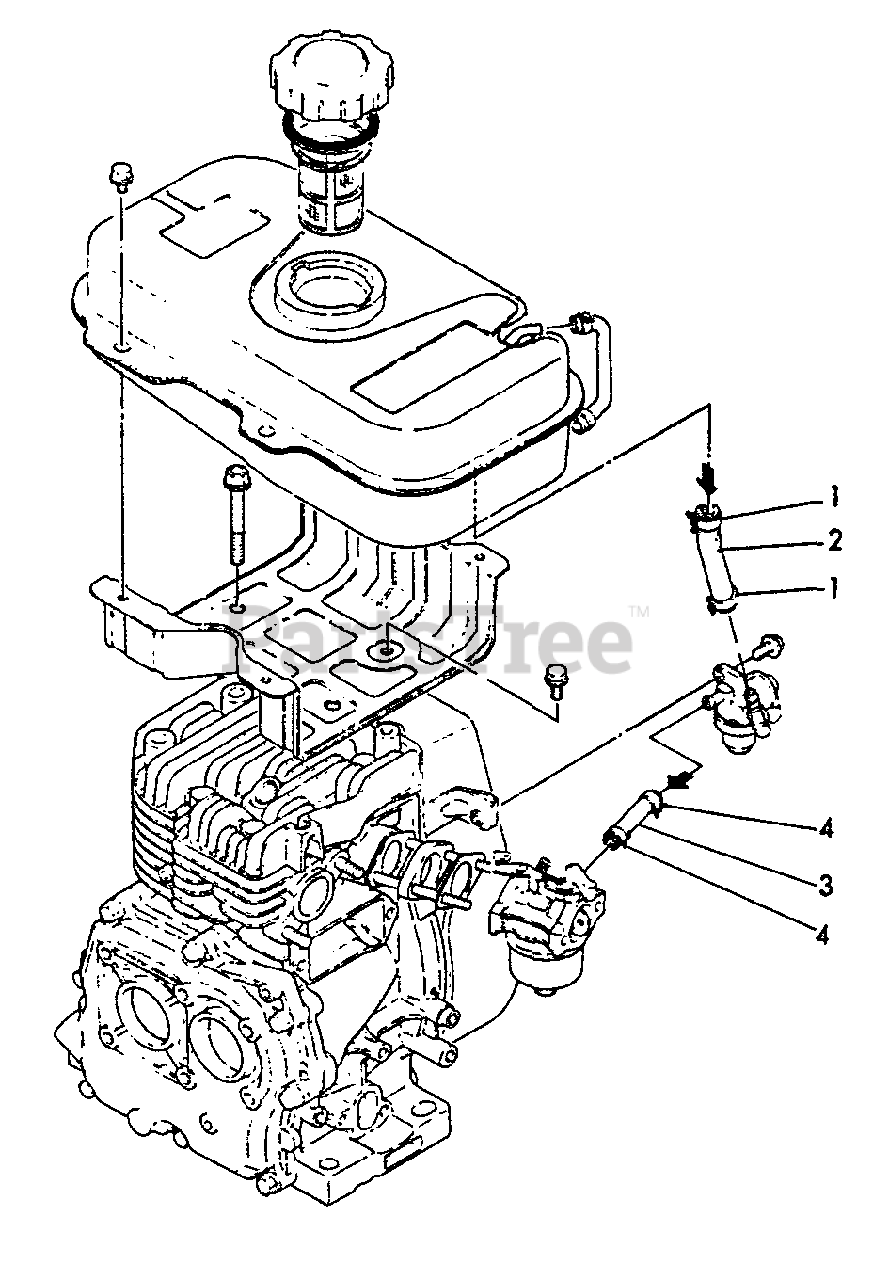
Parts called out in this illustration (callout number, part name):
1	CLAMP, HOSE
2	PIPE (A), FUEL
3	PIPE, FUEL
4	CLAMP
